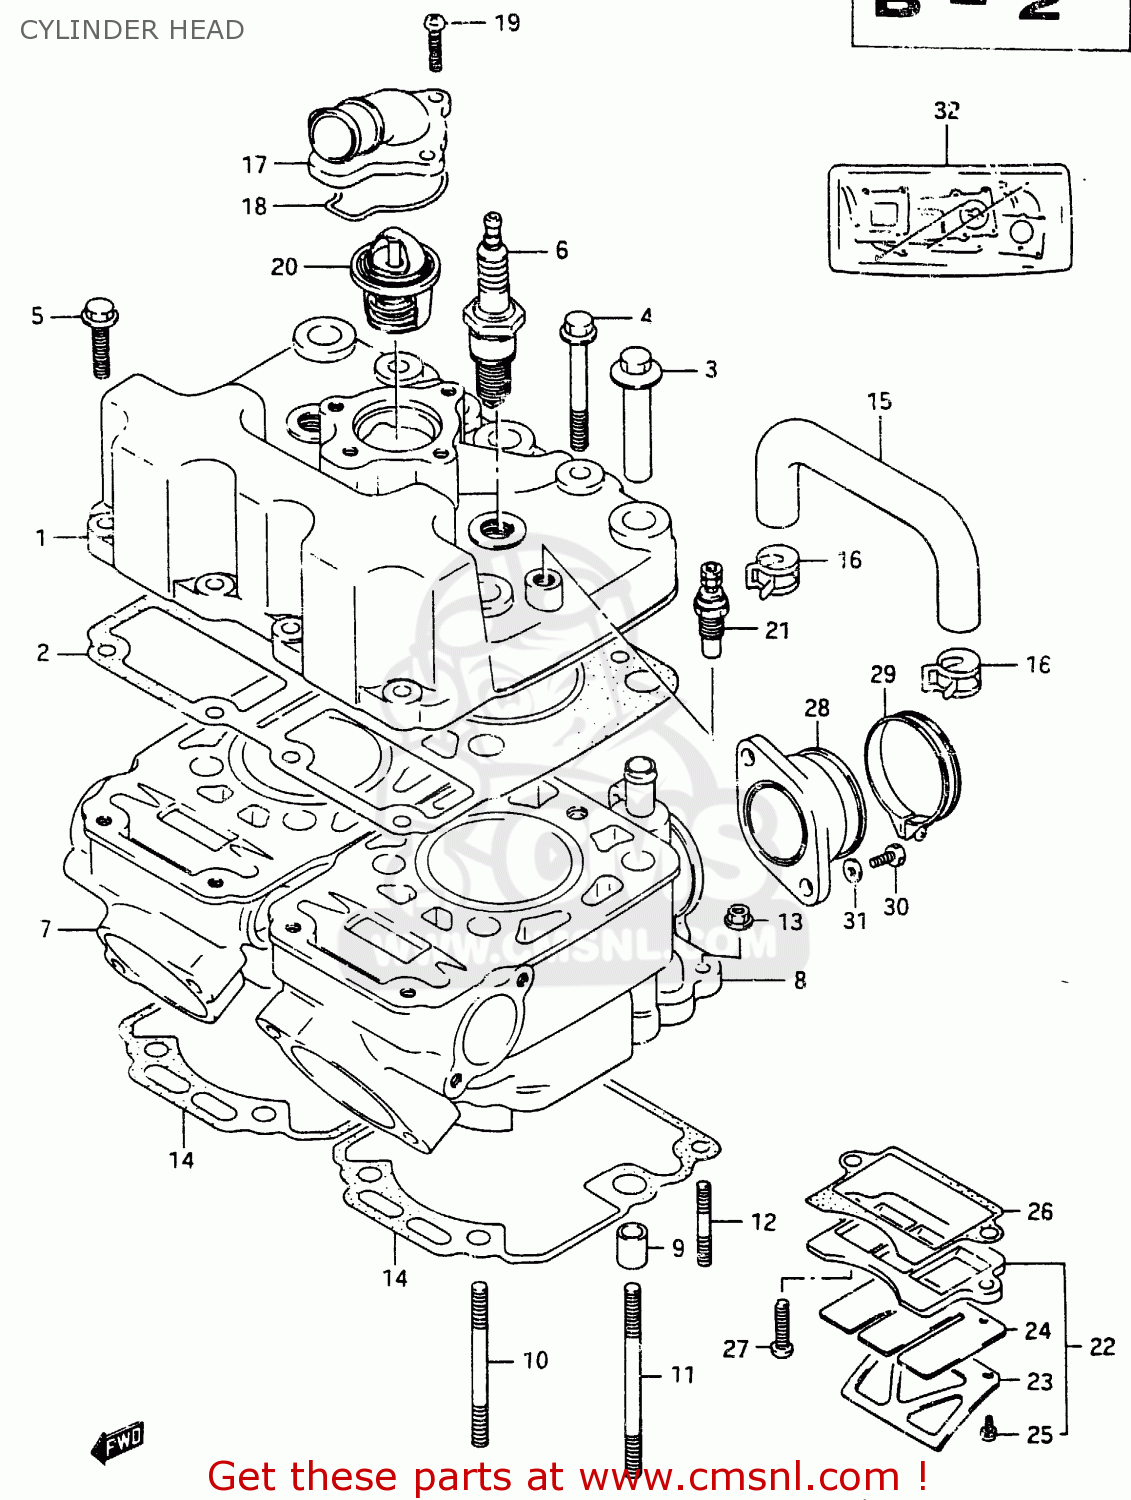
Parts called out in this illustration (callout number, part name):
1	HEAD, CYLINDER
2	GASKET, CYLINDER HEAD (MCA)
3	NUT
4	BOLT, UPPER
5	BOLT
6	SPARK PLUG B9ES
7	CYLINDER, RH
8	CYLINDER, LH
9	PIN
10	STUD BOLT (L:80)
11	BOLT,STUD
12	STUD BOLT L:20
13	NUT 6MM
14	GASKET,CYLINDE (MCA)
15	HOSE, JOINT
16	CLIP, HOSE
17	COVER, THERMOSTAT
18	O RING,THERMOSTAT COVER
19	SCREW
20	THERMOSTAT,WATER
21	GAUGE, WATER TEMP
22	VALVE ASSY, REED
23	STOPPER,REED VALVE
24	VALVE,REED
25	SCREW,REED VALVE
26	GASKET,REED VALVE (NAS)
27	SCREW
28	PIPE,INTAKE
29	CLAMP
30	BOLT 6X16
31	WASHER
32	GASKET SET (MCA)
